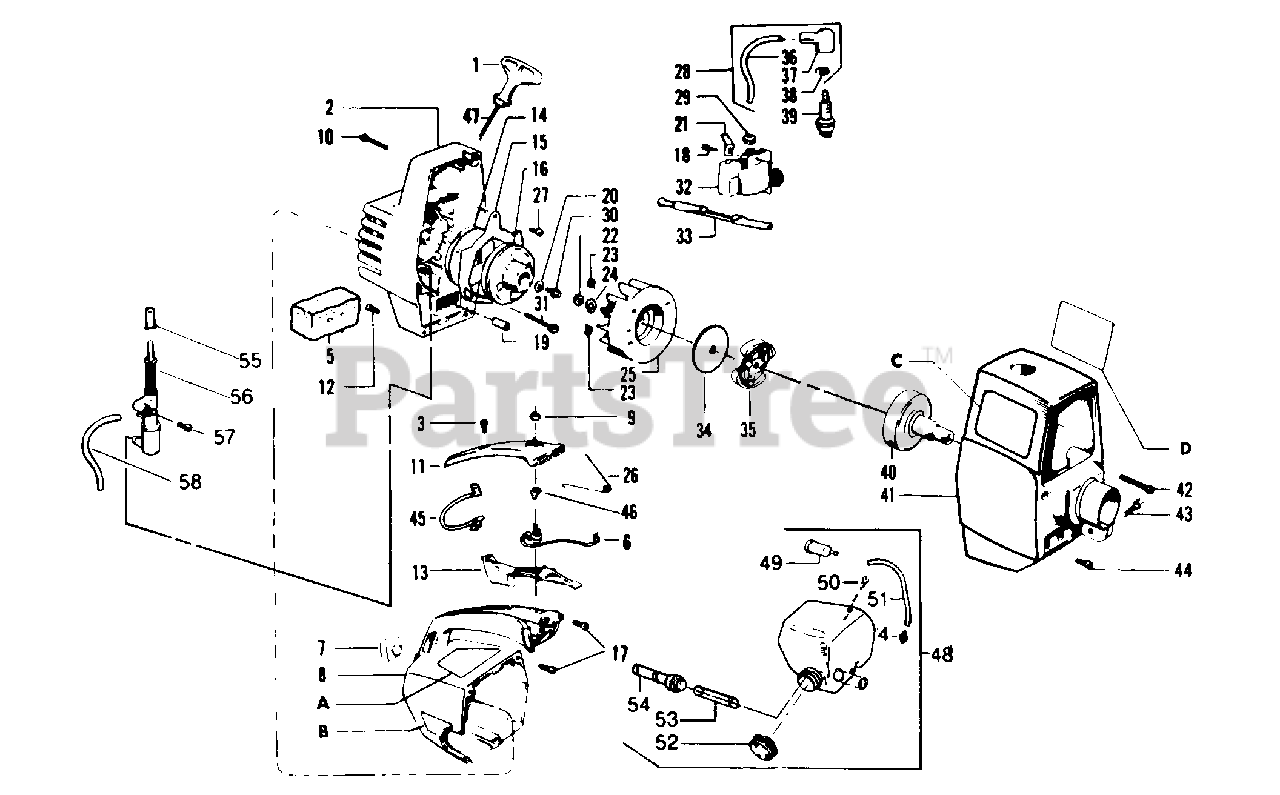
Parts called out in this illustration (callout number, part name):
1	Starter Handle
2	Fan Housing Kit (Incl. #15, 19, 27 & 31) -See Service Ref. 6.
3	Screw - Handle Cover - #8 - 16 x 3/4" - Pan Head
4	Fuel Line Fitting - Type 1 Only
5	Air Filter
6	Grounding Switch Kit (Incl. #9, 21, 45 & 46)
7	Fuel Tank Housing - Bumper
8	Handle & Fuel Tank Housing
9	Grounding Switch - Nut
11	Handle Cover
13	Trigger - Throttle
14	Type 2
15	Air Baffle - (Incl. #20)
17	Fan Housing to Handle & Fuel Tank - Screw - #10 - 14 x 3/4" - Pan Head
18	Ignition Module - Screw - #8 - 32 x 3/4" - Fil. Hd.
19	Spacer - Type 1 only
20	#10 Starter Pulley - Washer
21	Electrical Tab 45ø
22	Flywheel - Nut - #5/16 - 24" - Hex
23	Starter Dog - Spring
24	Flywheel - Washer
25	Flywheel Assembly (Incl. #23)
26	Trigger Spring
28	BEVEL GEAR COMPLETE
29	Plug Wire - Grommet
32	Ignition Module Kit
33	Choke Knob - Type 1 only
34	Clutch Washer - Kit
35	Clutch Assembly - Kit (Incl. Clutch Washer) See Service Ref. 1 & 5.
36	High Tension - Lead Wire
37	Spark Plug - Boot
38	Spark Plug Lead - Connector
39	Spark Plug (Champion CJ-14)
40	Clutch & Drive Adaptor - Drum
42	Shroud - Screw Top - #10 - 24 x 1-1/3" - Fil. Head
43	Pinch Clamp - Bolt - #1/4 - 20 x 1" - Hex Cap
44	Shroud - Screw Bottom - #10 - 24 x 5/8" - Fil. Head
45	Grounding Switch - Lead Wire
46	Grounding Switch Washer
47	Rope Kit
48	Fuel Tank Ass'y.
49	Fuel Pick-up Ass'y.
50	Duck Bill Valve
51	Fuel Line
52	Fuel Cap Ass'y.
53	Fuel Inlet Line
54	Fuel Filter (Inlet Line)
55	Injector Button
56	Pump Ass'y. (Incl. #58)
58	Pump to Accumulator Line
A	Starting Instruction Decal
B	Decal - Warning - Fuel Cap
C	Decal - Shroud (Right) (Not a serviceable part)
D	Decal - Shroud (Left) (Not a serviceable part)
